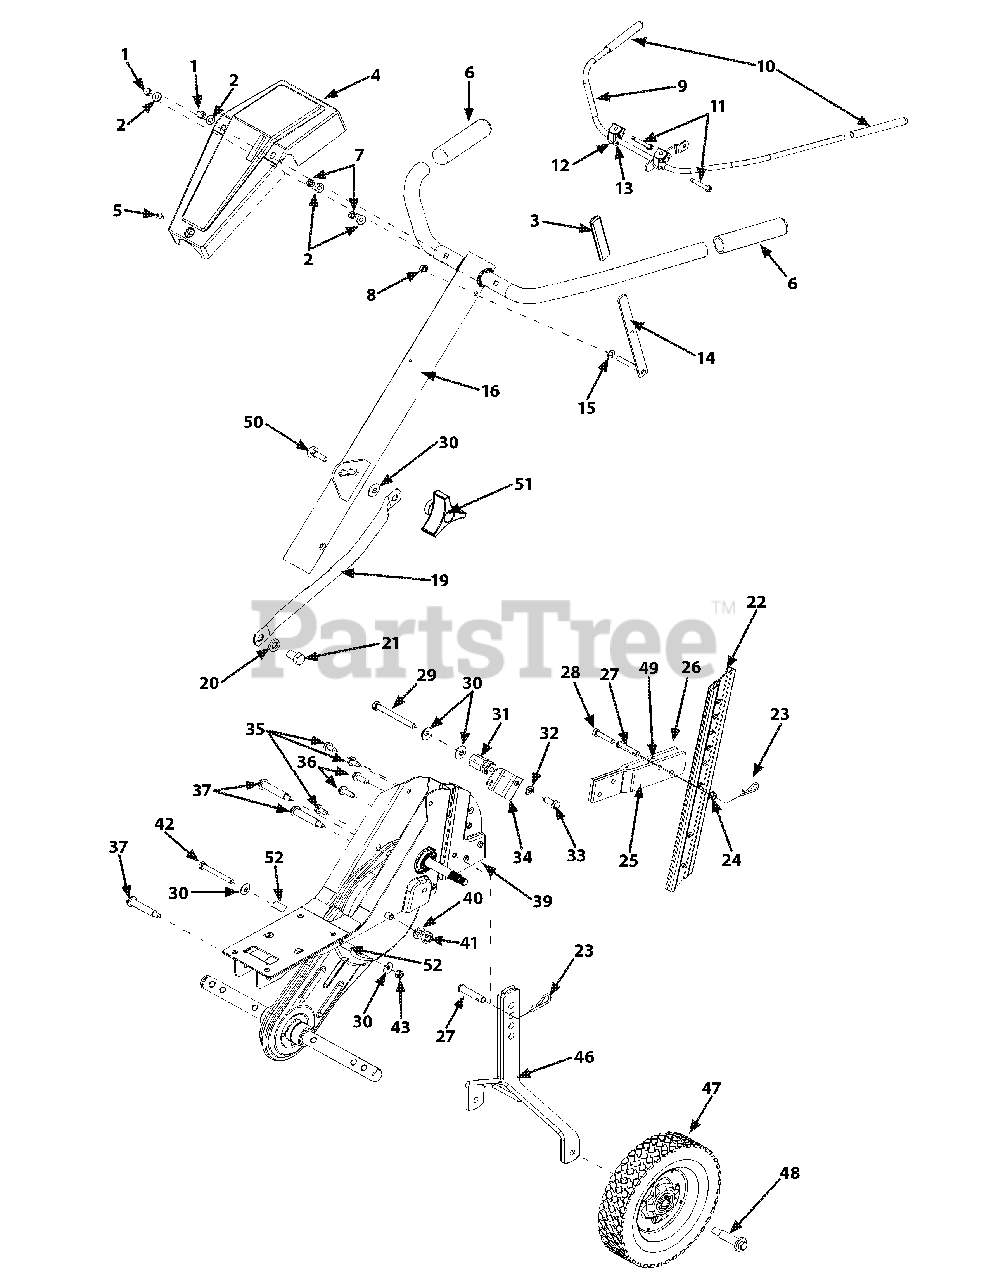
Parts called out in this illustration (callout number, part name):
1	Acorn Lock Nut, 1/4-20
2	Flat Washer, .271" I.D. x .630" O.D.
3	Reverse Handle Grip
4	Handle Cover w/o throttle
5	Truss Mach. Screw, #10 x 1/2" Lg.
6	Handle Grip
7	Hex Nut, 1/4-20 Gr. 2
8	Cap Speed Nut
9	Clutch Handle Assembly
10	Clutch Grip
11	Hex Bolt, 1/4-20 x 2.25" Lg. Gr. 5
12	Clutch Handle Holder
13	Flat Washer, .385" I.D. x .62" O.D.
14	Reverse Handle Assembly
15	Flat Washer, .344" I.D. x .62" O.D.
16	Handle Assembly Comp.
19	Handle Brace
20	Lock Washer, 1/2''
21	Hex Bolt, 1/2-20 Gr. 5
23	Cotter Pin
24	Hex Flange L-Nut, 5/16-18 Thd. Gr. 5
25	Tail Piece Bracket, Left
26	Tail Piece Bracket, Right
27	Clevis Pin
28	Hex Bolt, 5/16-18 x 1.5" Lg.
29	Hex Bolt, 5/16-18 x 3" Lg.
30	Washer Bell, .340" I.D. x .872" O.D.
31	Spec. Hex Nut
32	L-Washer, 5/16" I.D.
33	Hex Bolt, 5/16-18 Gr. 5
34	Cable Guide Bracket
35	Hex Washer Screw, 5/16-18 x .62" Lg.
36	Hex Washer Hd. TT-Tap Screw
37	Shoulder Bolt, 5/16-18
40	Lock Washer, 7/16
41	Jam Nut, 7/16-20 Gr. 2
42	Hex Bolt, 5/16-18 x 2.75" Lg.
43	Hex Nylon Nut, 5/16-18
46	Wheel Hanger Bracket Assembly
47	Wheel Assembly, 8" x 1.75" (Plastic)
48	Shldr. Screw, .496 I.D. x 1.445 O.D.
50	Carriage Bolt, 5/16-18 x 1
51	Hand Knob
